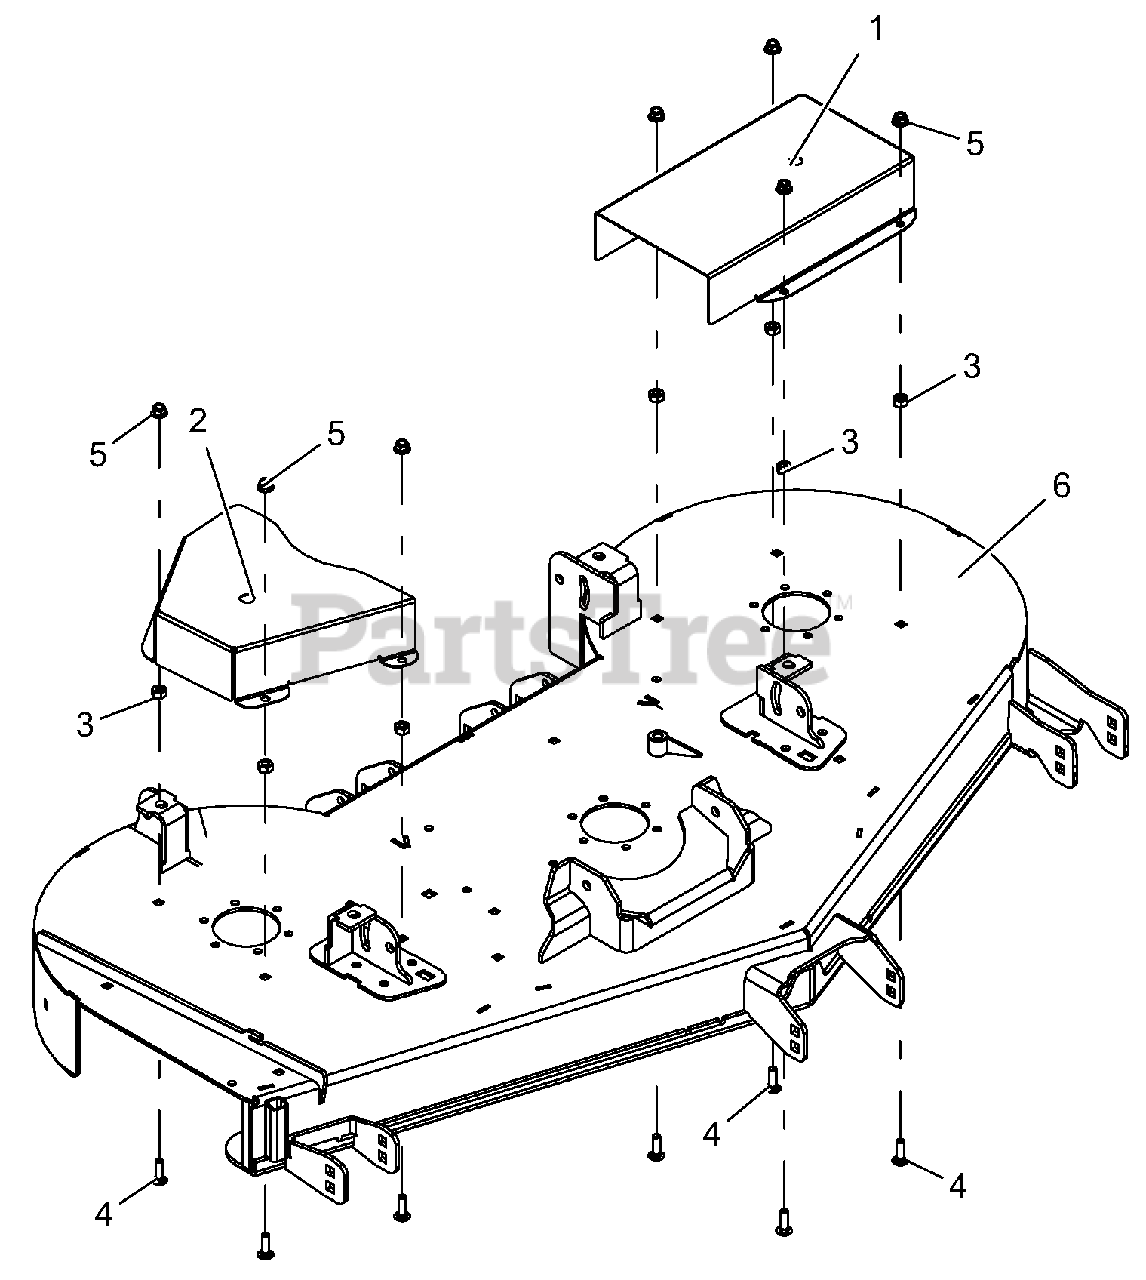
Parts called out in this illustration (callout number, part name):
1	GUARD, 61" LH DECK BELT
2	GUARD, 61" RH DECK BELT - RED
3	NUT-HEAVY HEX .38-16 YWZC
4	BLT-RDHDSQNK .38-16 x 1.25 G5 YWZC
5	NUT-LK-NYL-FLG .38-16 YWZC
6	WLDMT, DECK 61" PROSTANCE - RED
